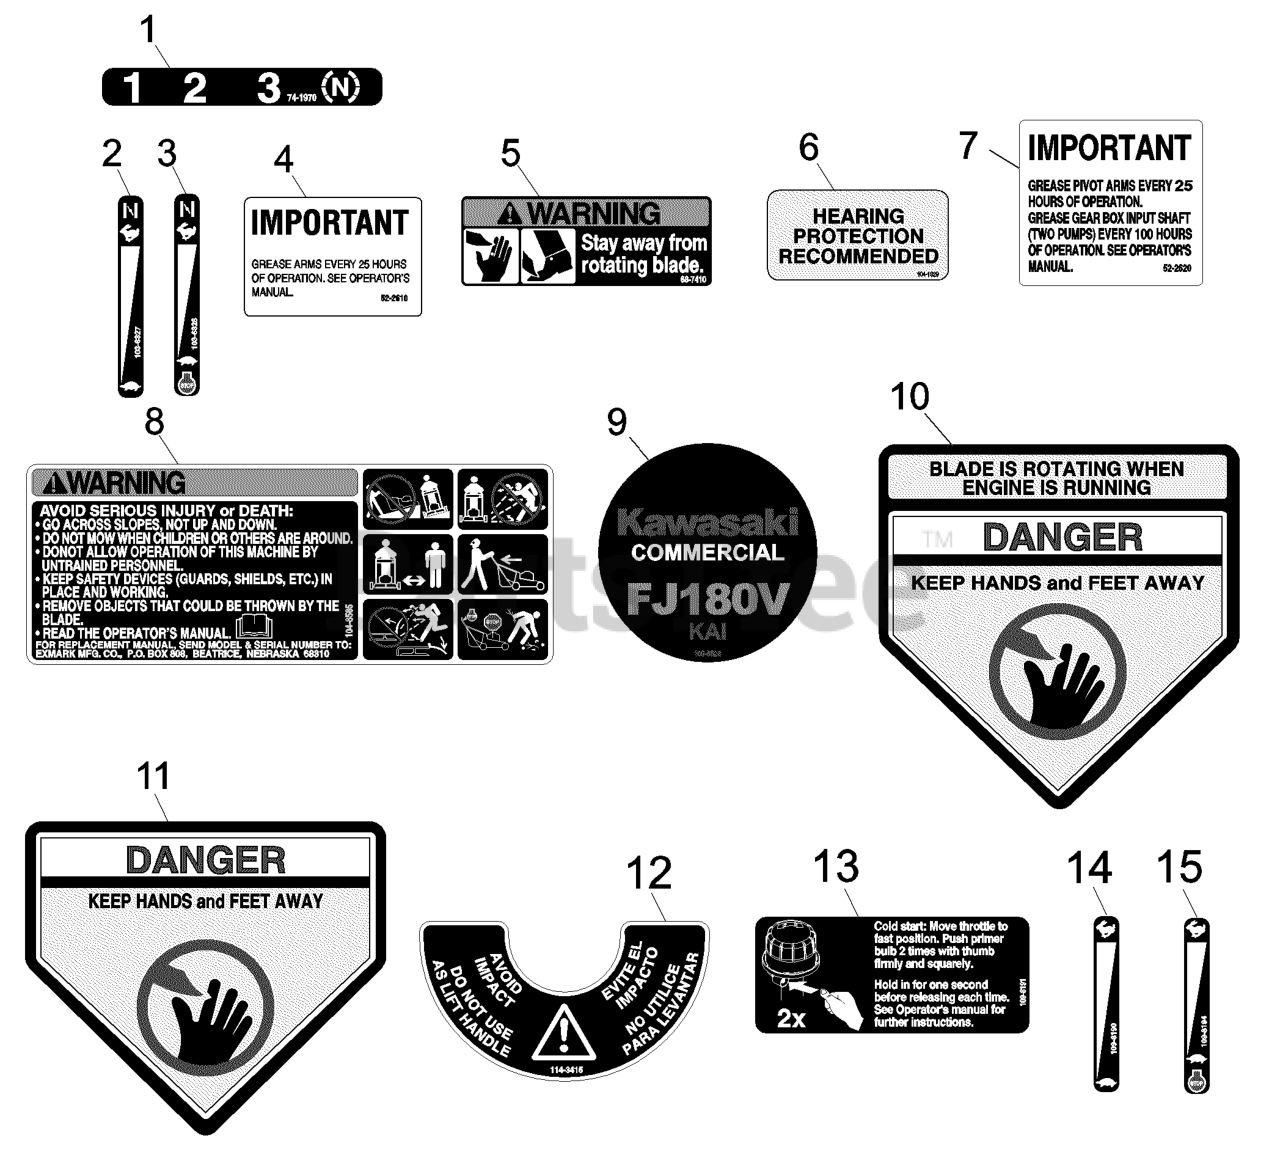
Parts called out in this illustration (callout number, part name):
1	DECAL-POSITION, GEAR
2	DECAL,THROTTLE/CHOKE
3	DECAL-THROTTLE / CHOKE
4	LABEL-GREASE, HP
5	DECAL-BLADE
6	DECAL-PROTECTION, HEARING
7	Label, Grease
8	DECAL-WARNING
9	DECAL
10	DECAL-DANGER
11	DECAL-DANGER
12	DECAL
13	DECAL, PRIMER
14	DECAL, THROTTLE CONTROL Z
15	DECAL THROTTLE CONTROL BB
